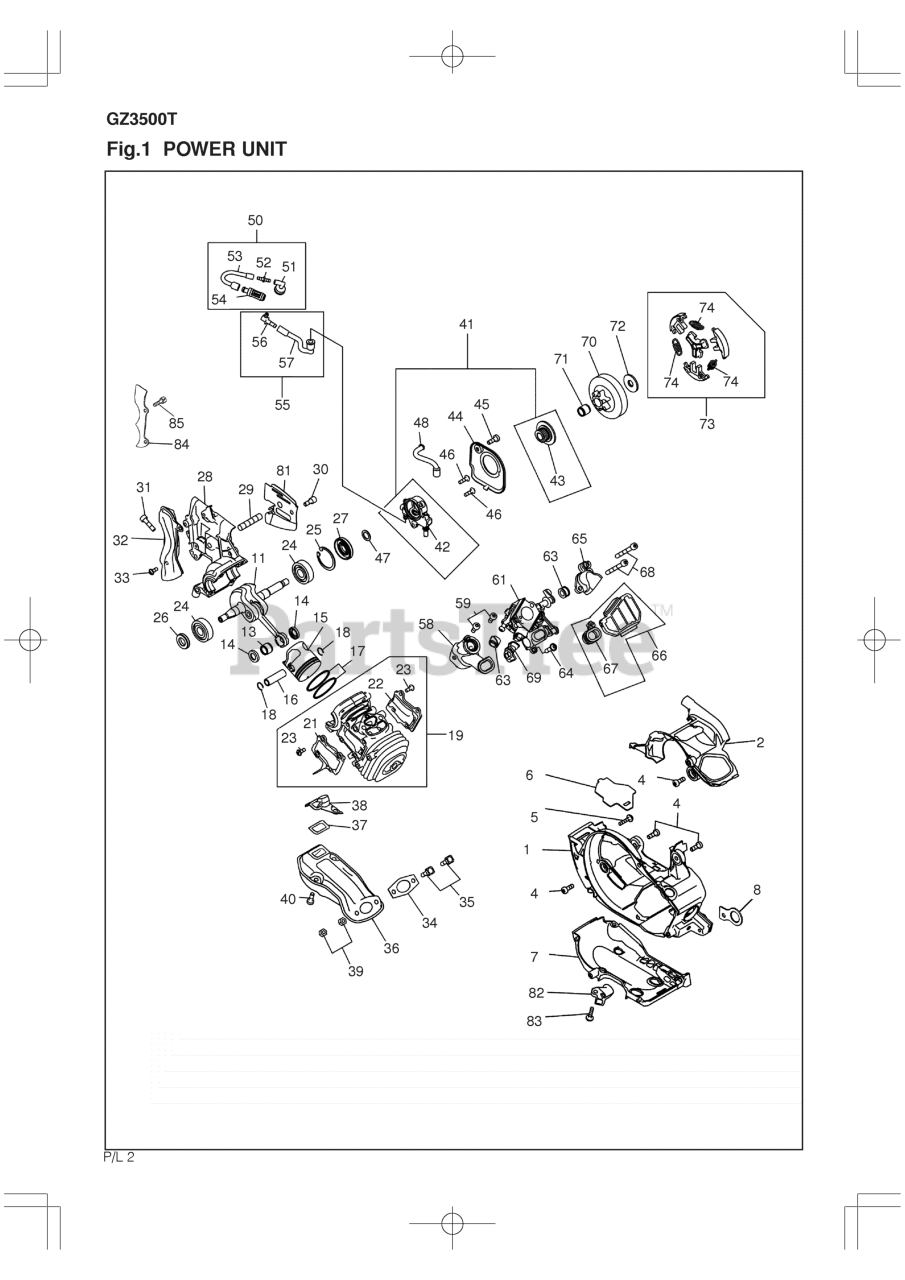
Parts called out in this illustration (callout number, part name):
1	CASE, EG
2	COVER, TOP
4	SCREW
5	SCREW
6	GASKET
7	GUARD, UNDER
11	SHAFT, COMP
13	BEARING
14	WASHER
15	PISTON
16	PIN
17	RING, PISTON
18	RING, SNAP
19	CYLINDER ASSY
21	TR, COVER MAG
22	TR, COVER PTO
23	SCREW
24	BEARING
25	SNAP RING
26	SEAL
27	SEAL
28	CASE, CRANK
29	STUD
30	BOLT
31	BOLT TORX
32	PIPE, EXHAUST
34	GASKET, MUFFLER
35	BOLT
36	MUFFLER
38	GUIDE, MUFFLER
39	NUT
40	SCREW
41	OIL PUMP SET(RPLS 284155112)
42	OIL PUMP
43	WORM
44	COVER, PUMP
45	SCREW
46	SCREW
47	THRUST WASHER
48	PIPE
50	FILTER COMP
51	PIPE, OIL FILTER
52	JOINT
53	PIPE
54	FILTER
55	PIPE IN COMP
56	ELBOW
57	PIPE, OIL IN
58	PIPE, INLET
59	BOLT
61	CARBURETOR ASSY
63	SEAL
64	SCREW
65	MANIFOLD
66	CLEANER ASSY
67	SEAL
69	GUIDE, CAB
71	BEARING
73	CLUTCH-ASSY
74	SPRING
81	PLATE
82	CATCHER (RPLS -66F1)
83	SCREW
85	SCREW
